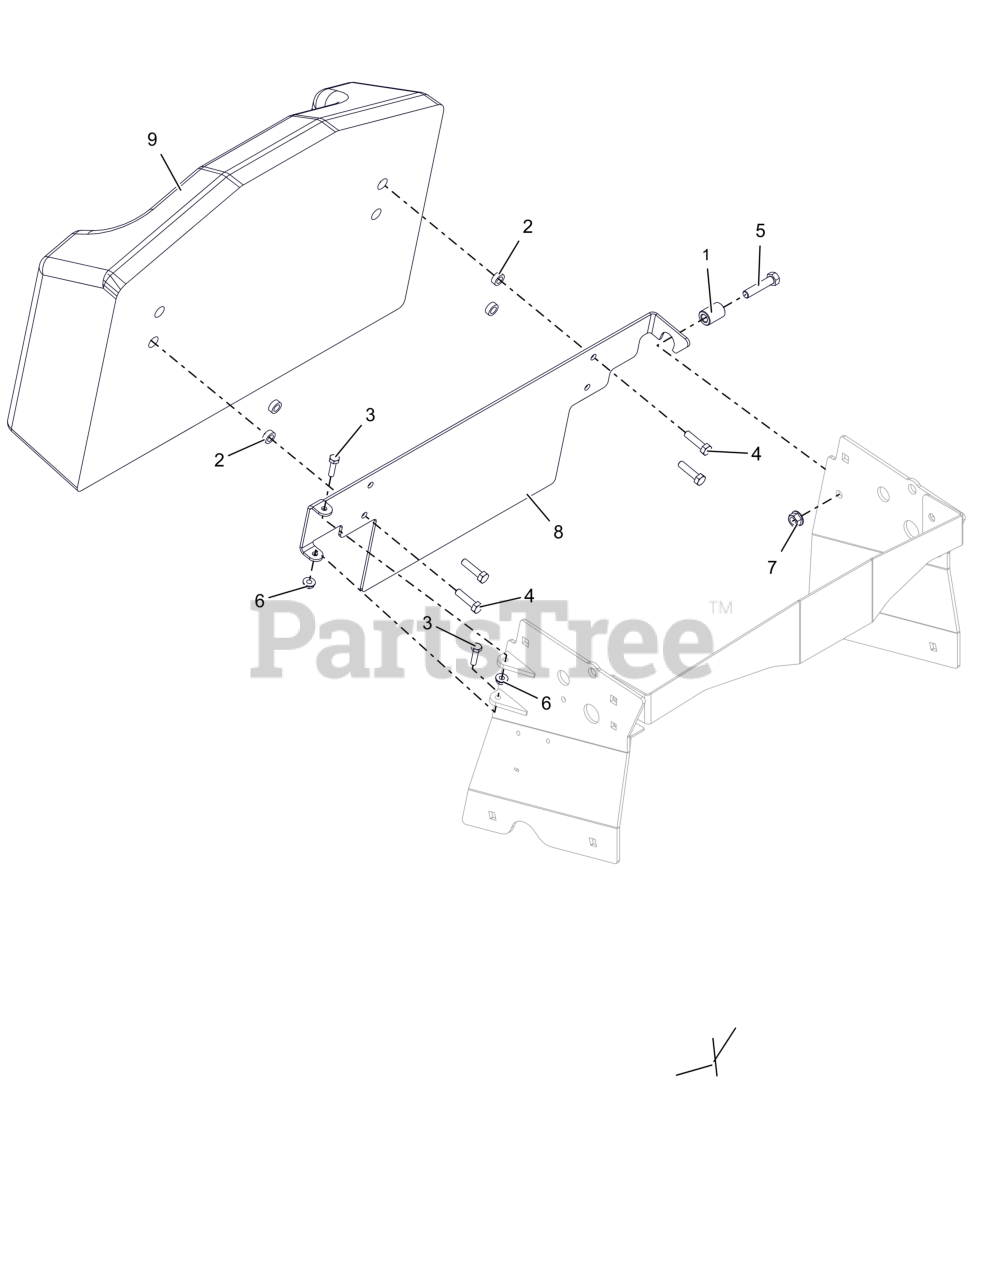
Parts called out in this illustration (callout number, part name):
1	SPCR, .750 OD X .390 ID X 1.063
2	BSHG-SLV .377X.624X.235
3	BLT,HEX .25-20X1.00 G5 ZCC
4	BLT, HEX .31-18X1.25 G5 ZCC
5	BLT, HEX .38-16X1.75 G5 ZCC
6	NUT-LK-CTR-FLG .25-20 ZC120
7	NUT-LK-CTR-FLG .375-16 GF ZCC
8	BRKT, OPERATOR PAD MTG (ORANGE)
9	PAD- OPERATOR
